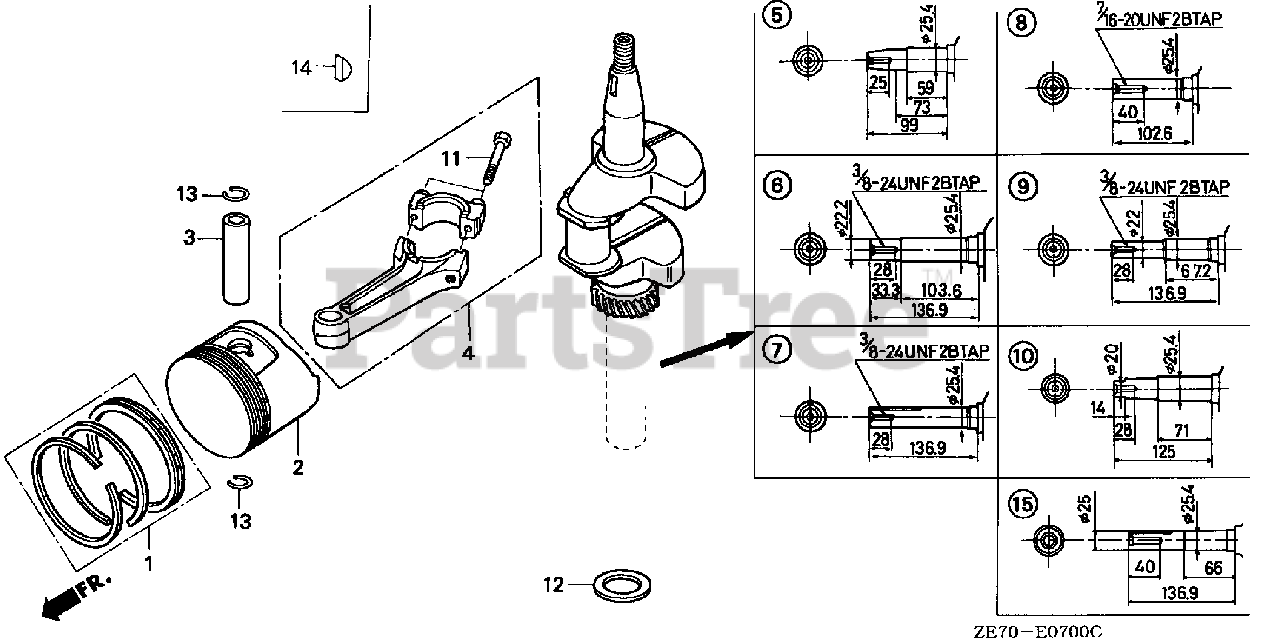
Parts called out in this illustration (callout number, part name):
1	RING SET, PISTON (STD) (TEIKOKU)
1	RING SET, PISTON (STD) (NIPPON)
1	RING SET, PISTON (0.25)
1	RING SET, PISTON (0.50)
1	RING SET, PISTON (0.75)
2	PISTON (STD)
2	PISTON (0.25)
2	PISTON (0.50)
2	PISTON (0.75)
3	PIN, PISTON
4	ROD ASSY., CONNECTING
6	CRANKSHAFT
11	BOLT, CONNECTING ROD
13	CLIP, PISTON PIN (18MM)
